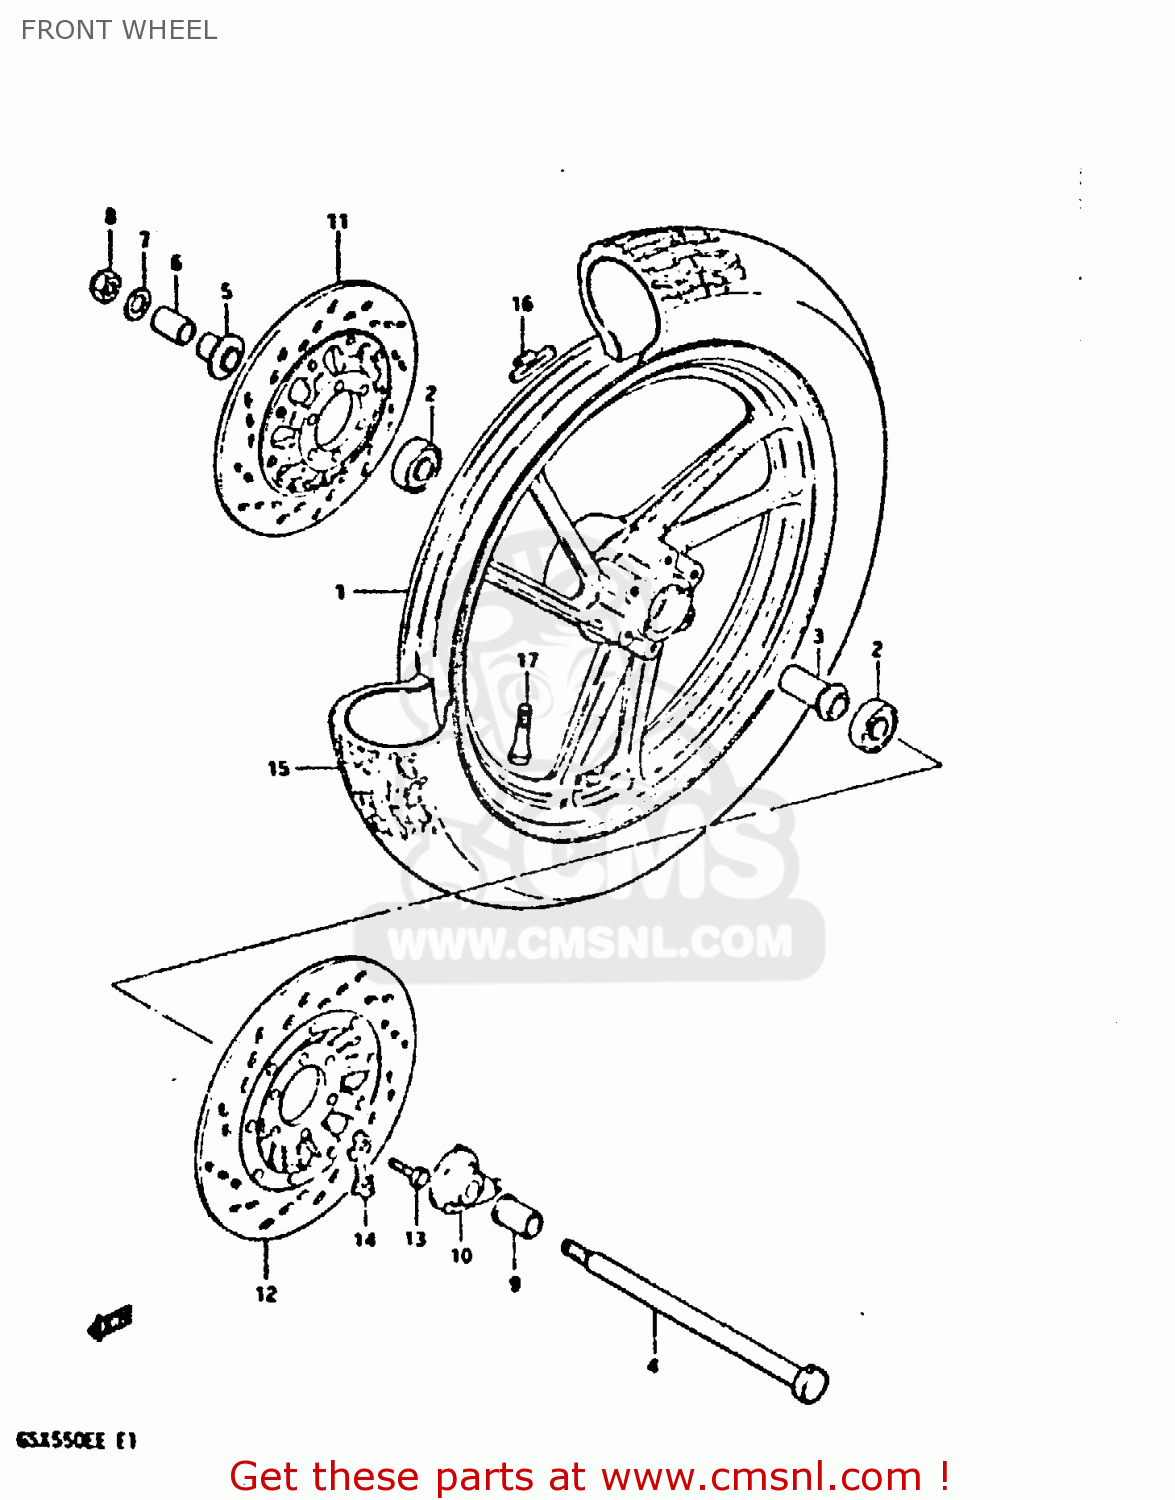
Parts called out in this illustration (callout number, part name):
1	WHEEL,FRONT
2	BEARING
3	SPACER,FR HUB BEARING
4	AXLE,FR
5	SPACER,FR AXLE,R
6	SPACER,FR AXLE,R
7	WASHER
8	NUT
9	SPACER,FR AXLE,L
10	BOX ASSY,SPEEDOMETER GEAR
11	DISC,BRAKE,RIGHT
12	DISC,BRAKE,LEFT
13	BOLT(8X30)
14	WASHER
15	TIRE,FRONT
16	BALANCER,WHEEL
17	VALVE,TIRE
